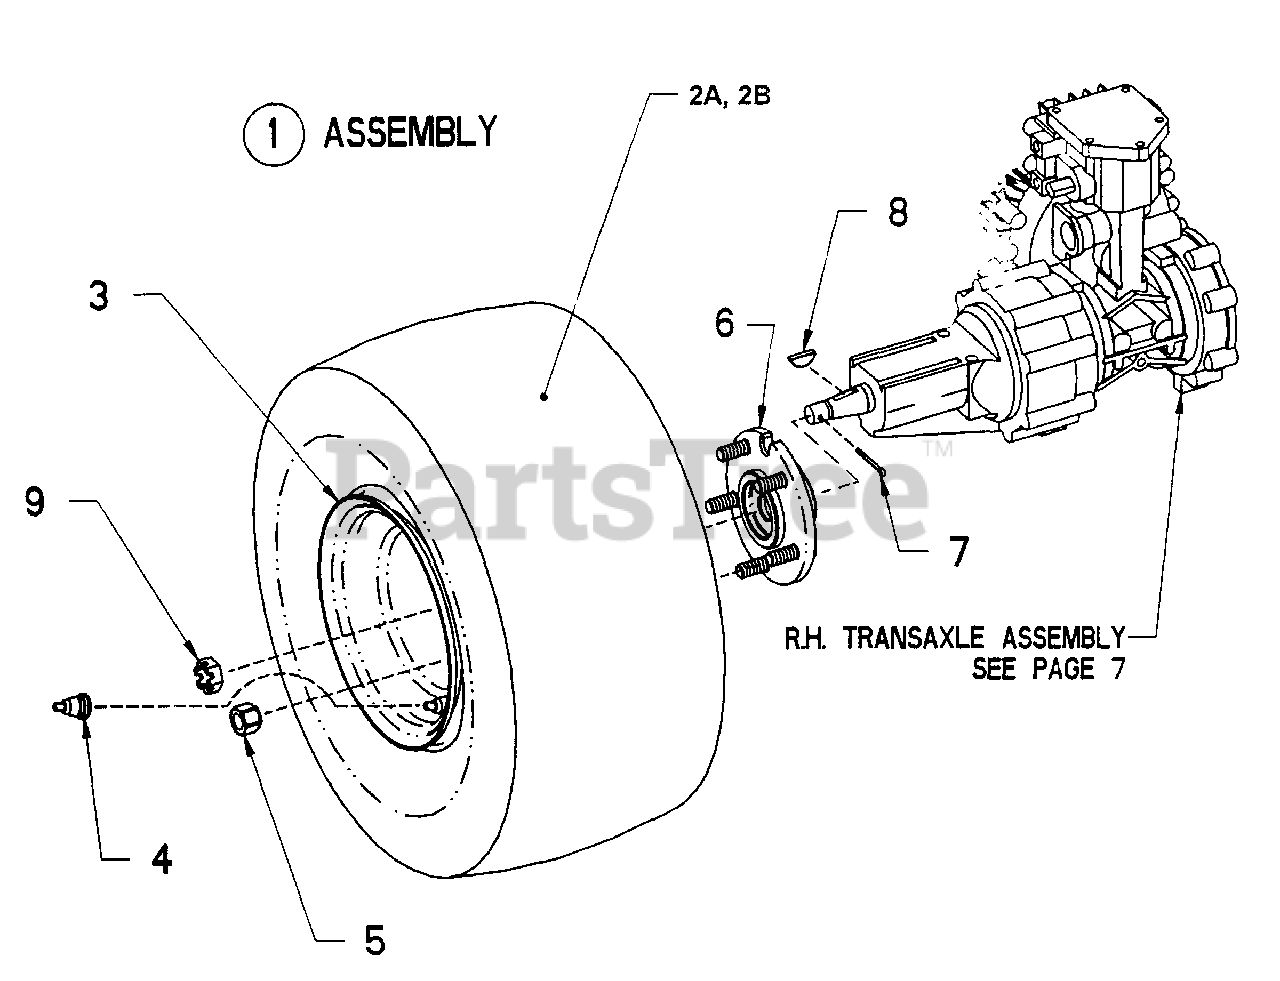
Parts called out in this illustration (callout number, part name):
1	ASSEMBLY, Rear Tire & Rim
2A	TIRE, 20 x 10.00-8 4 ply "Multi-trac C/S"
2B	TIRE, 21 x 11.00-8 "All Terrain 101"
3	RIM, 8" Dia. X 7-3/4"
4	VALVE, Air
5	NUT, 1/2-20 Lug (5)
6	ASSEMBLY, Wheel Hub
7	PIN, Cotter, 9/64 x 1-1/2
8	KEY, #808 Woodruff
9	NUT, 3/4-20 Slotted Hex
